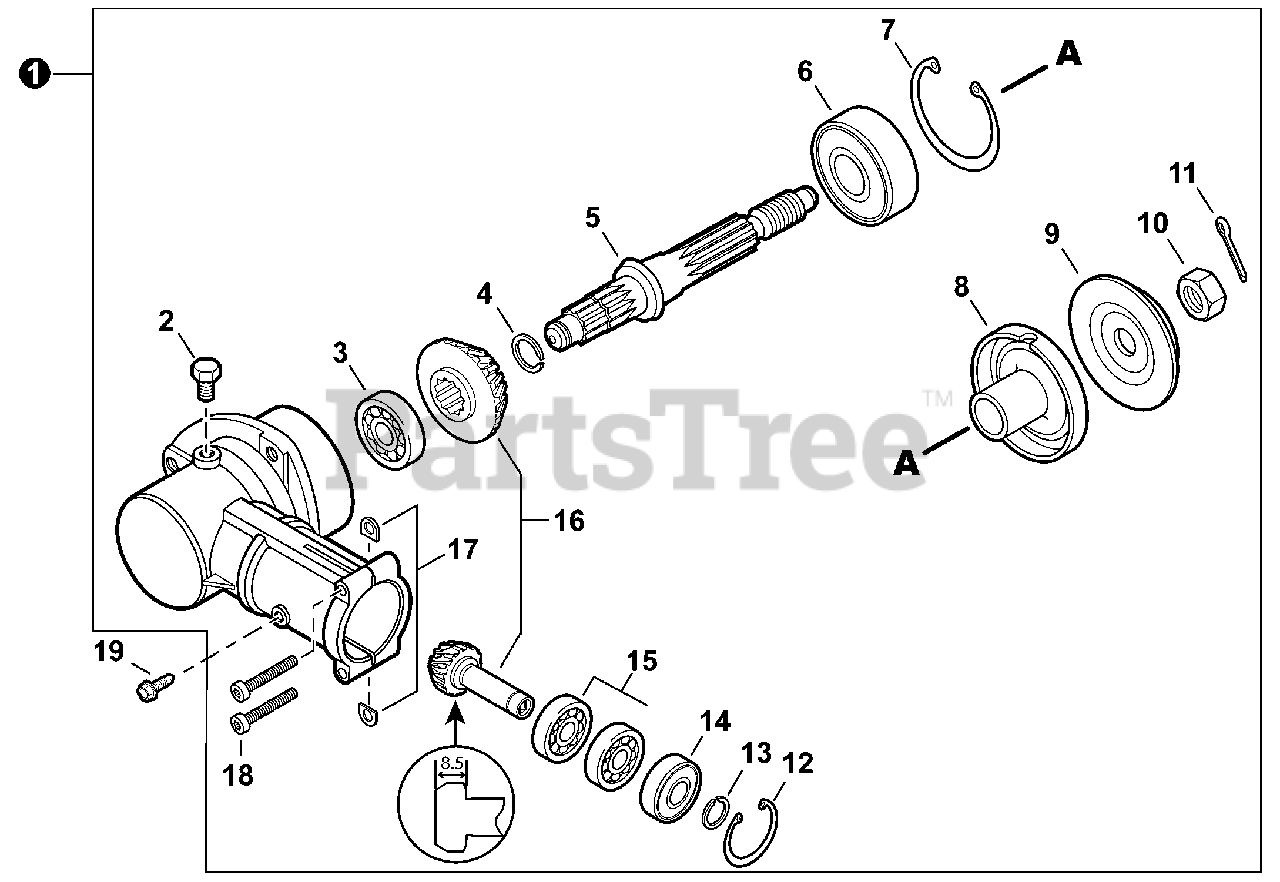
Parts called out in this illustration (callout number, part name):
1	GEAR CASE ASSY
2	BOLT M8×8
3	BEARING, BALL 629
4	RING, SNAP Ø12
5	SHAFT, GEAR
6	BEARING, BALL 6302
7	RING, SNAP Ø42
8	PLATE, ADAPTOR - UPPER
9	PLATE, ADAPTOR - LOWER
10	NUT 10×1.25 LH
11	PIN, COTTER 2×22
12	RING, SNAP Ø22
13	RING, SNAP Ø10
14	BEARING, BALL 6900Z
15	BEARING, BALL 6900
16	GEAR SET
18	BOLT, TORX 5×25
19	BOLT, 5 SELF DRILLING
